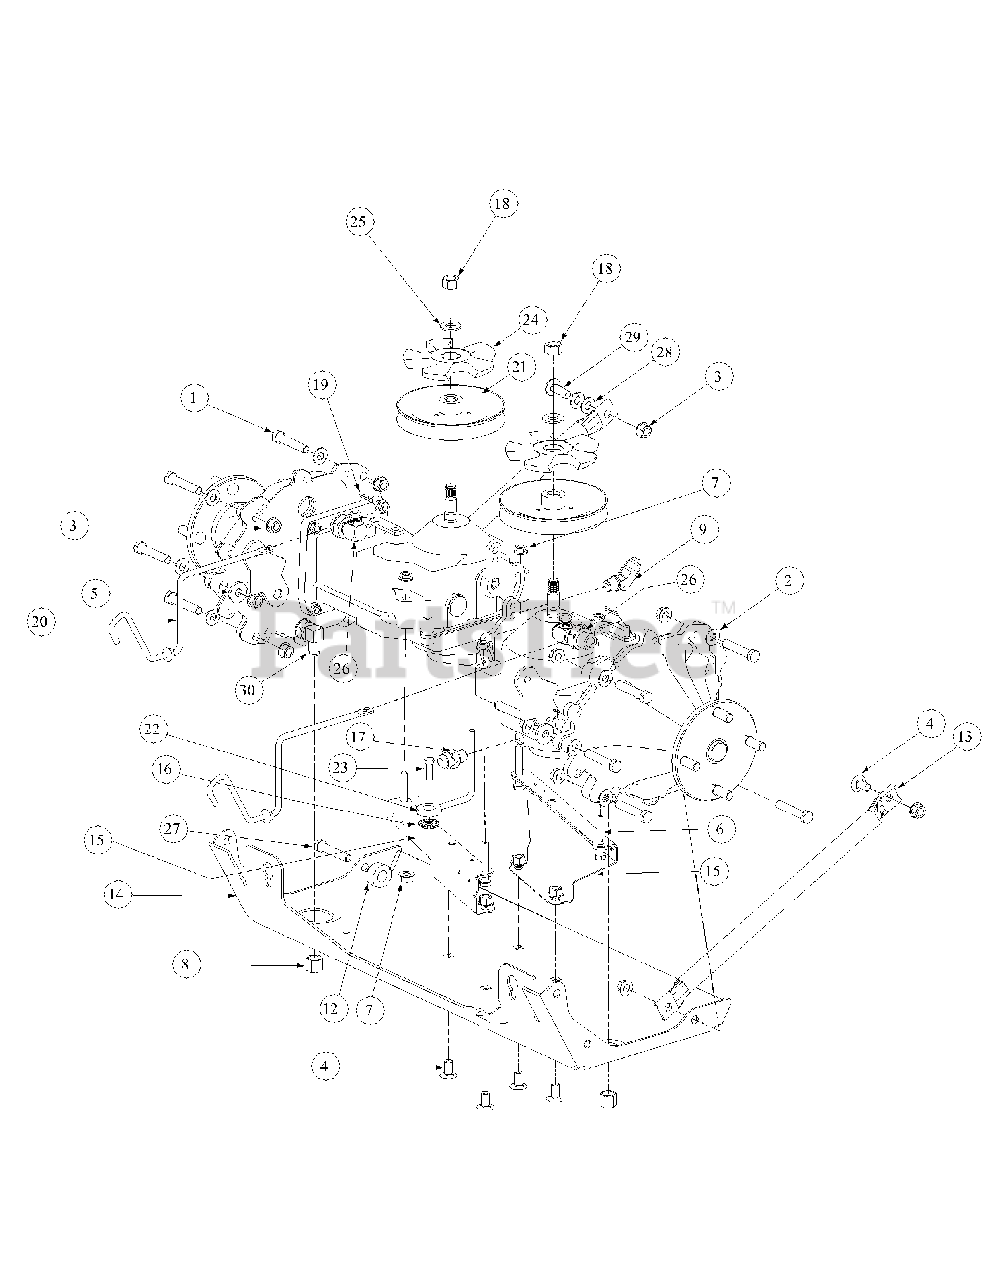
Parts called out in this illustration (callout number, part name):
1	HHCS, 3/8-16, 2.00
2	Flat Washer, 3/8, SAE
3	Hex Nut, 3/8-16, Flange Lock
4	Carriage Bolt, 3/8-16 x .75 Long
5	Flat Washer, .385 x 1.0 OD x .13
6	HHCS, 5/16-18, 2.00
7	Lock Nut, Hex Flange, 5/16-18
8	Nut, Cap, 3/8
9	Elbow Fitting, 3/8-1/2, 45 degree
12	Spacer, .406 ID x 1.00 OD x .38
14	Plate Assembly, Skid
15	Bracket Assembly, Support Pump
16	External Tooth Washer
17	Fitting Connector, 1/2 x 3/8
18	Nut, 1/2-20, Hex Insert Lock Jam
19	Hair Pin, .0721 x 1.12 Long
20	Rod, Release, Pump
21	Pulley, Transmission Hydro, Slotted
22	Guide, Traction Drive Belt
23	Flat Head Screw, 5/16-18 x 1.00
24	Hydro Pulley Fan
25	1/2" Flat Washer
26	Fitting Elbow, 1/2 x 3/8
27	Hex Cap Screw, 3/8-16, 2.50
28	Lock Washer, 3/8
29	Carriage Bolt, 3/8-16 x 1
30	Fitting Elbow, 3/8 x 3/8
